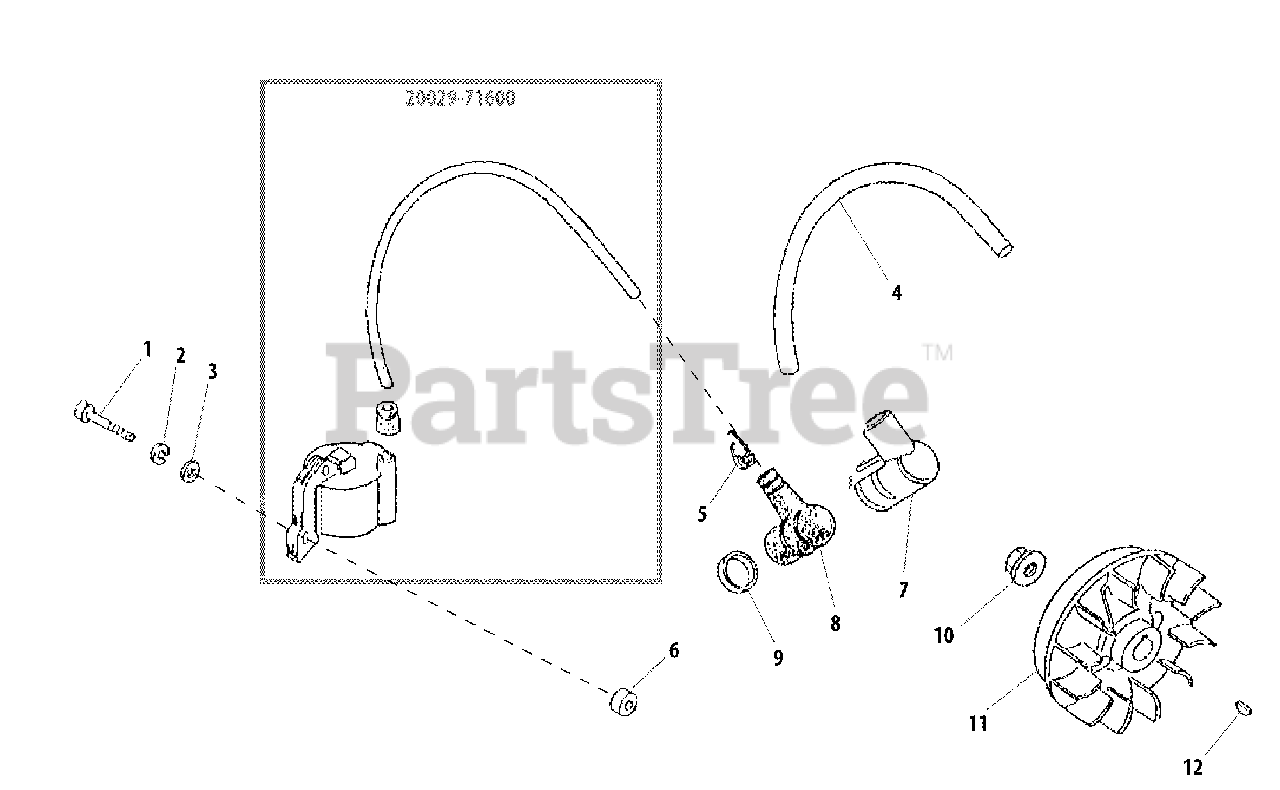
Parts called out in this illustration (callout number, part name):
1	SCREW - 4X26
2	LOCKWASHER - 4
3	WASHER - 4
4	TUBE
5	TERMINAL, SPARK PLUG CAP
6	INSULATOR
7	CAP, SPARK PLUG
8	CAP, SPARK PLUG
9	SEAL, DUST
10	NUT - 8
11	FLYWHEEL
12	KEY - 3X10
A	IGNITION COIL ASSY
